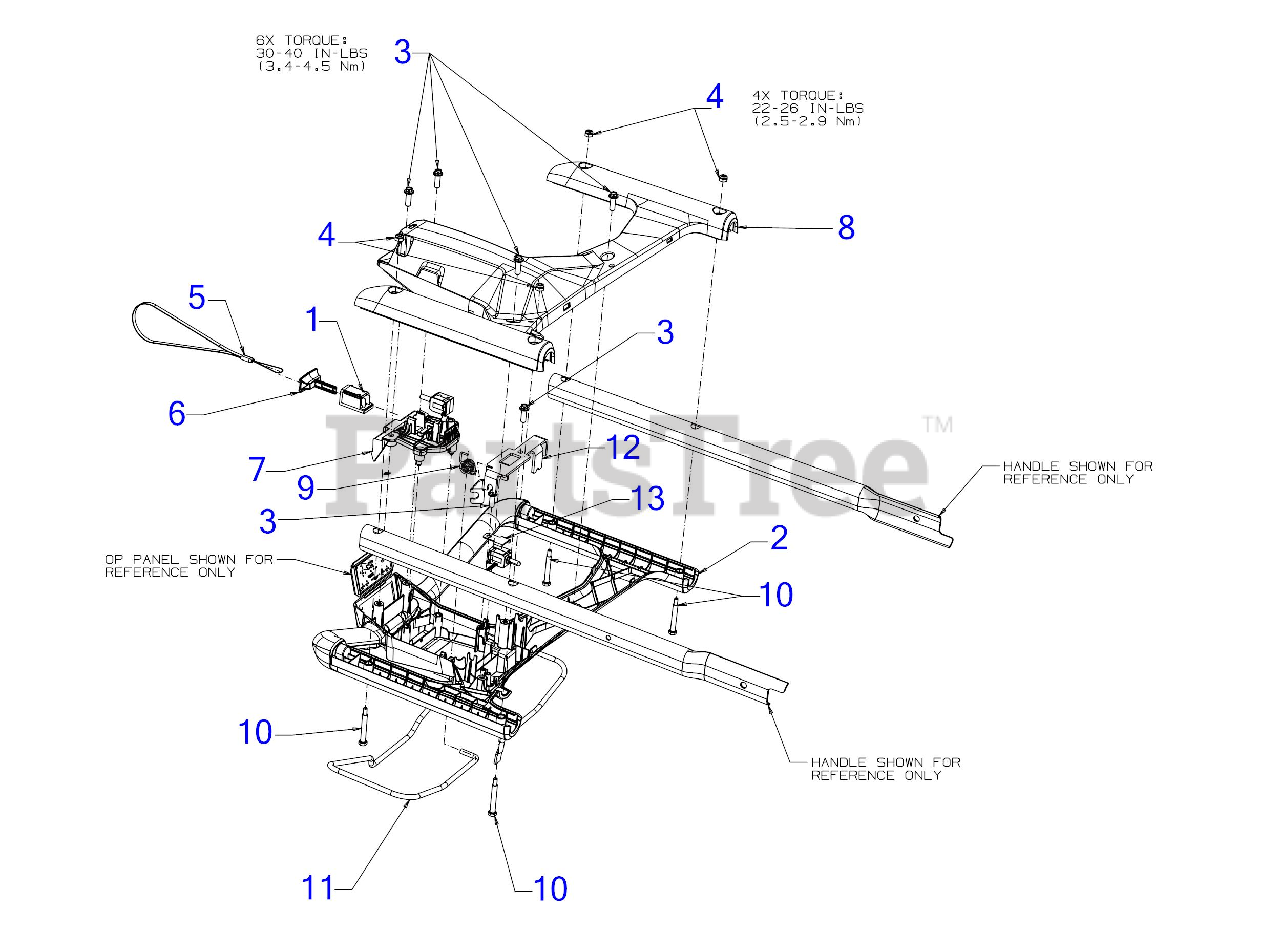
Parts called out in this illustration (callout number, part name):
1	KEY RECEPTICAL
2	UPPER HANDLE PANEL ASSEMBLY
3	SCREW-HEX INDWSH B
5	KEY STRAP CORE
7	KEY RECEPTICLE BRACKET
8	LOWER HANDLE PANEL
9	TORSION SPRING
10	SHOULDER SCREW .25:1.63:#10-24:.32
11	CONTROL BAIL
12	BAIL SUPPORT BRACKET
13	BAIL SWITCH BRACKET
